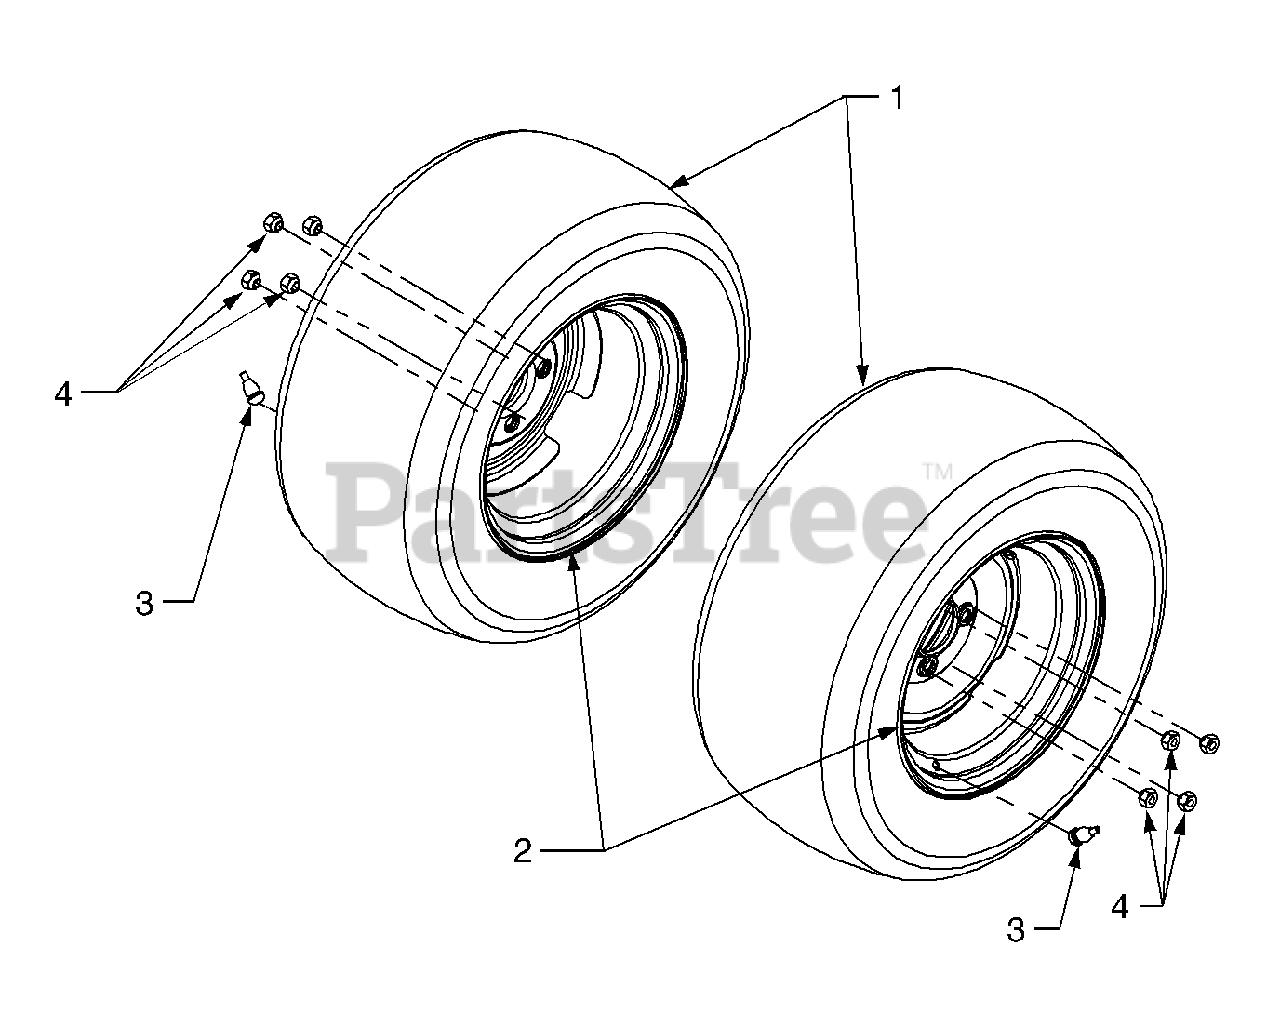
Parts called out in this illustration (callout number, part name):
1	Tire, Turf, 23 x 9.5 - 12
2	Rim Assembly, Wheel
3	Valve, Tubeless Air
4	Lug Nut, 7/16-14
